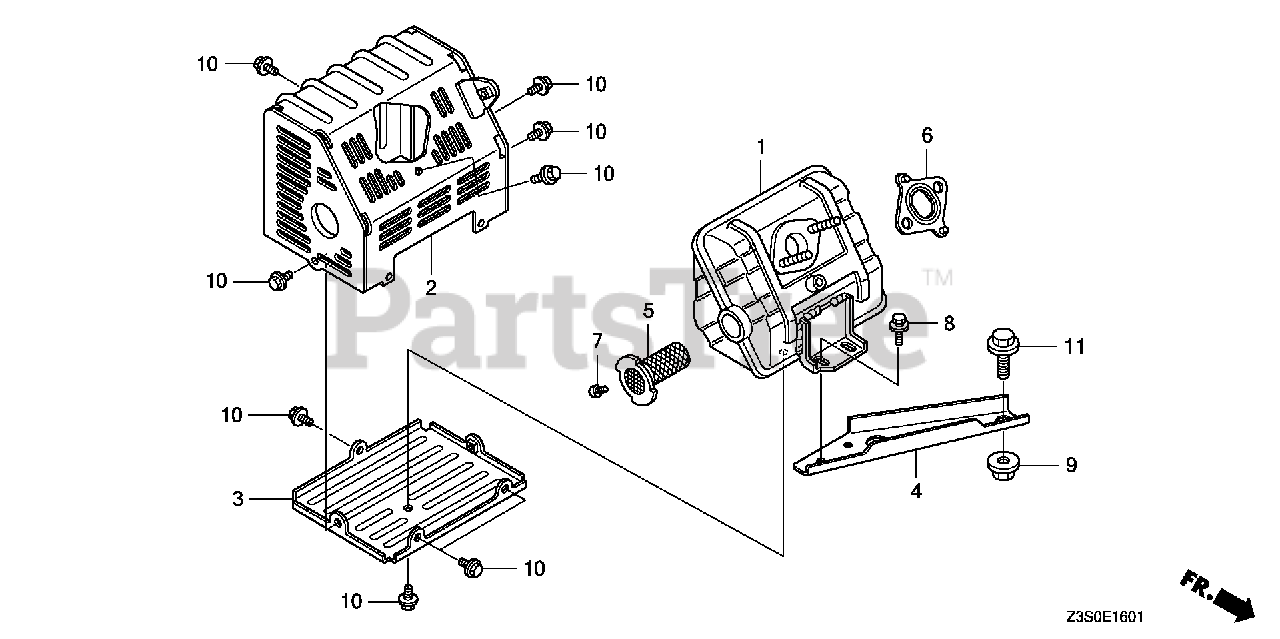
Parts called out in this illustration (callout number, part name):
2	PROTECTOR, MUFFLER
3	PROTECTOR, MUFFLER (LOWER)
4	STAY, MUFFLER
5	ARRESTER, SPARK
6	GASKET, MUFFLER (B)
7	SCREW, TAPPING (5X8)
8	BOLT-WASHER (6X16)
9	NUT, FLANGE (10MM)
10	BOLT, FLANGE (6X8)
11	BOLT, FLANGE (10X35)
